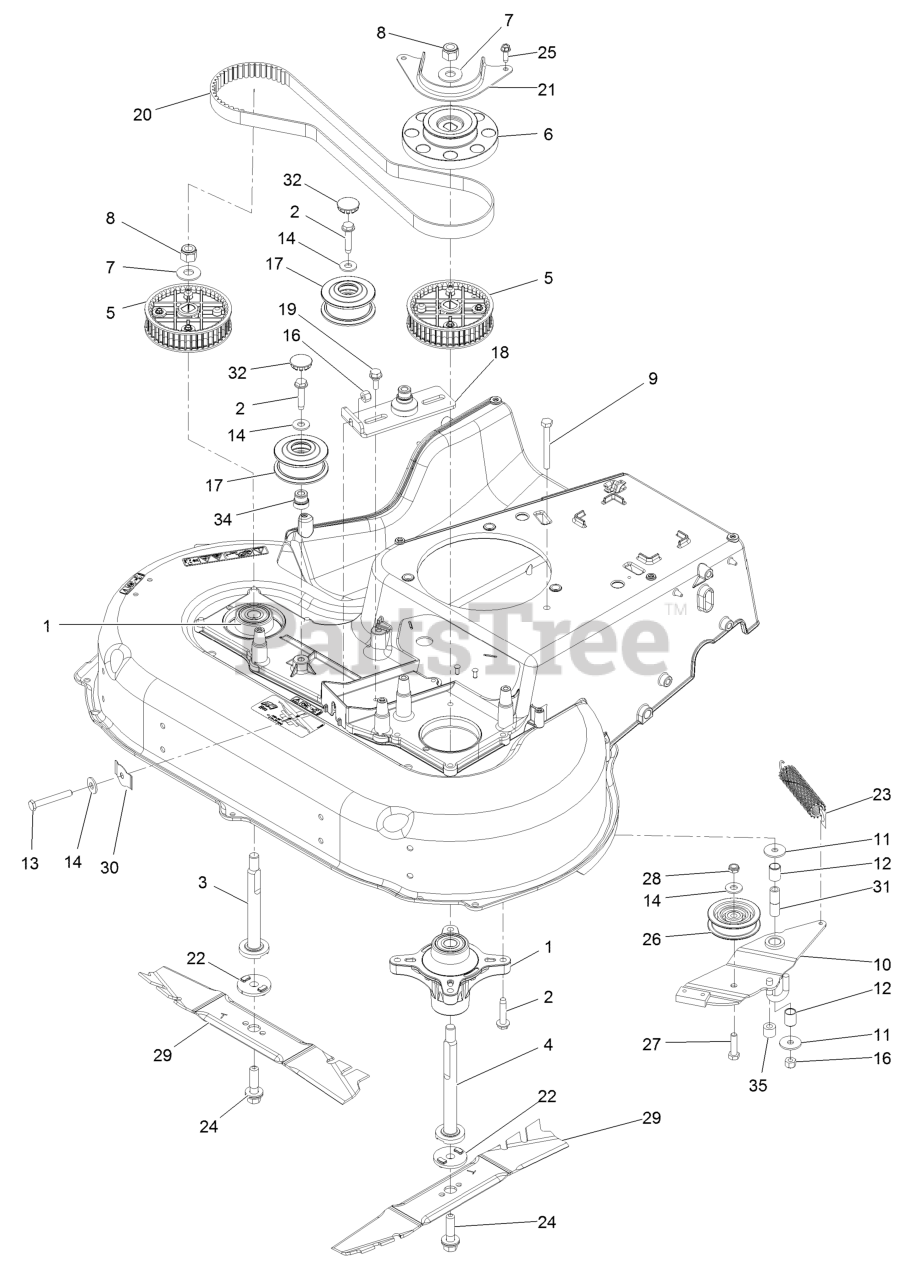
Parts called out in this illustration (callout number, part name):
3	SHAFT-SPINDLE
4	SHAFT-SPINDLE
5	SPROCKET
6	PULLEY-BRAKE, SPINDLE
7	WASHER-SPRING
8	NUT-HEX
9	SCREW-HH
10	BRAKE ARM ASM
11	WASHER-PIVOT
12	BUSHING-SLEEVE
13	BOLT-TAP, HH
14	WASHER-FLAT
16	NUT-LOCK, NI
17	PULLEY-IDLER, FLAT
18	BRACKET-IDLER
19	SCREW-SHOULDER,HWH
20	BELT-SYNCHRONOUS
21	GUIDE-BELT, SPINDLE
22	ADAPTER-BLADE
23	SPRING-EXTENSION, BRAKE
24	BOLT-BLADE
25	SCREW-HWHTF
26	PULLEY-IDLER
27	SCREW-HH
28	NUT-LOCK, NI
29	BLADE-ROTARY
30	SPRING-FLAT
31	SPACER-BRAKE
32	PLUG-BUTTON
34	ADAPTER-BORE
35	HOSE-COOLANT
